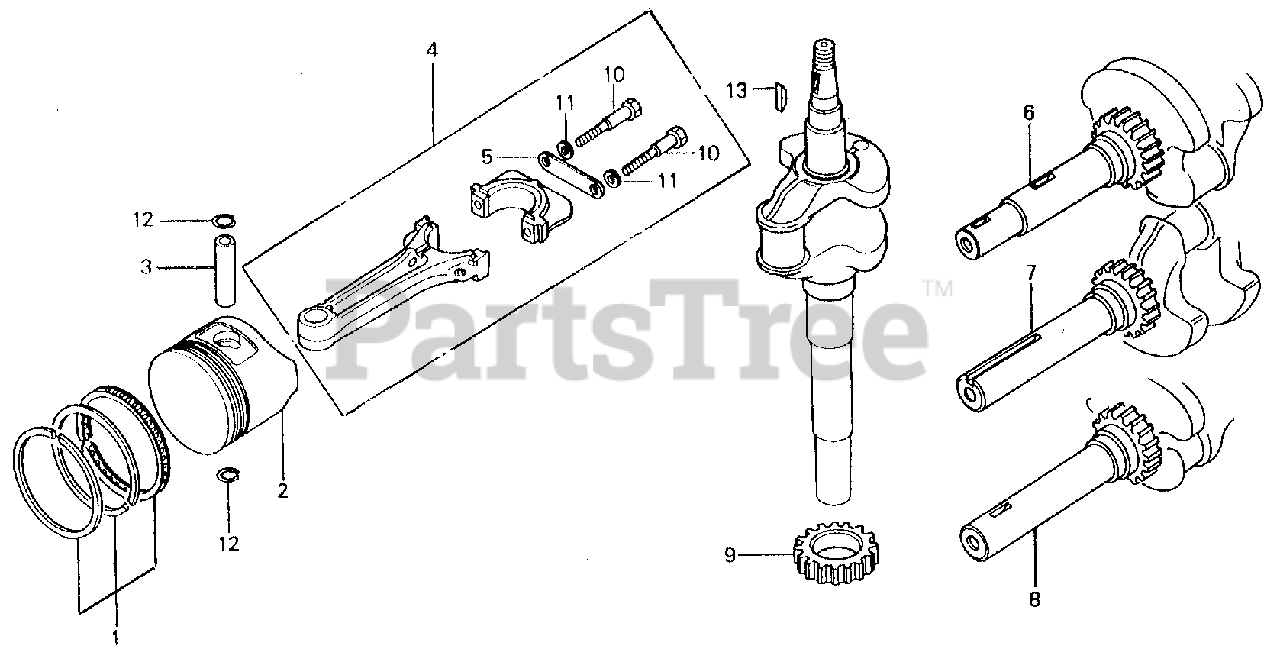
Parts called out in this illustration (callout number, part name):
1	RING SET, PISTON (STD)
1	RING SET, PISTON (OS 0.25)
1	RING SET, PISTON (OS 0.50)
1	RING SET, PISTON (0.75)
2	PISTON (STD)
2	PISTON (OS 0.25)
2	PISTON (OS 0.50)
2	PISTON (0.75)
3	PIN, PISTON
4	ROD ASSY., CONNECTING
4	ROD ASSY., CONNECTING (US 0.25)
5	WASHER A, CONNECTING ROD
5	WASHER, CONNECTING ROD
7	CRANKSHAFT
9	GEAR, TIMING
10	BOLT, CONNECTING ROD (6MM) (NOT AVAILABLE)
10	BOLT, CONNECTING ROD (7MM)
11	WASHER, LOCK (6MM) (N/A: SEE ASSEMBLY)
11	WASHER, LOCK (7MM)
12	CLIP, PISTON PIN (15MM)
13	KEY, SPECIAL WOODRUFF (25X18)
